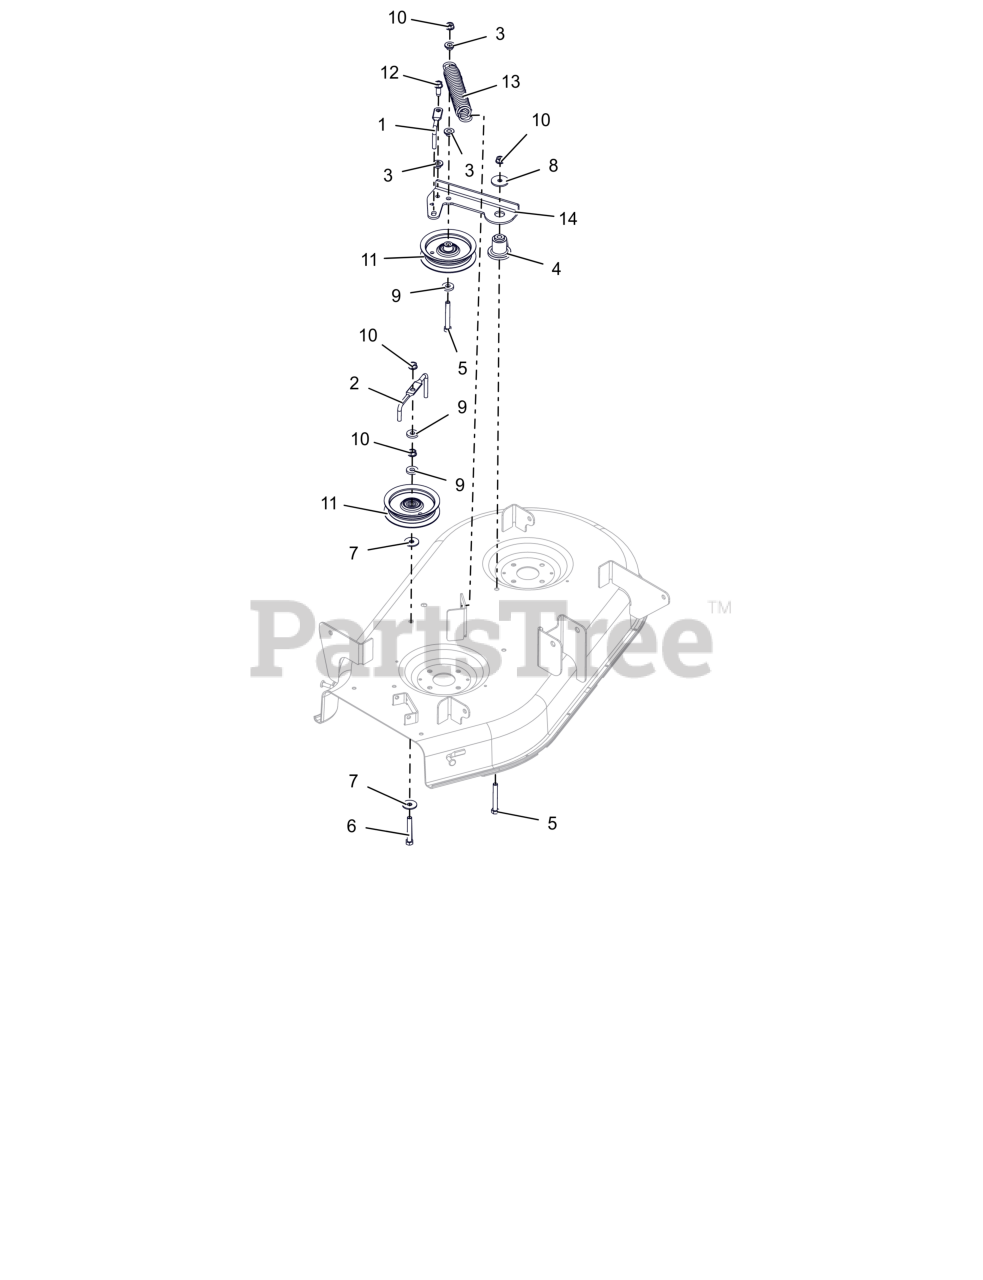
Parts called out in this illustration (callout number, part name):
1	WIREFORM-BELT FINGER
2	BELT FINGER
3	BSHG-FLG .385X.500X.875X.406
4	BSHG, FIXED IDLER
5	BLT, HEX .38-16X2.75 G5 ZCC
6	BLT, HEX .38-16X2.50 G5 ZCC
7	WSHR FL STL .406X1.25X.10ZC120
8	WSHR, FLT .380X1.50X.125 ZCC
9	WSHR, FLT .406X1.00X.188 ZCC
10	NUT-LK-CTR-FLG .375-16 GF ZCC
11	IDLER, FLAT - 4.06" X .75"
12	SCR-TAP .38-16X1.00 HWH TR ZCC
13	SPRG, EXTENSION .170X1.385X6.7
14	ARM, IDLER -34 ZT (RED)
